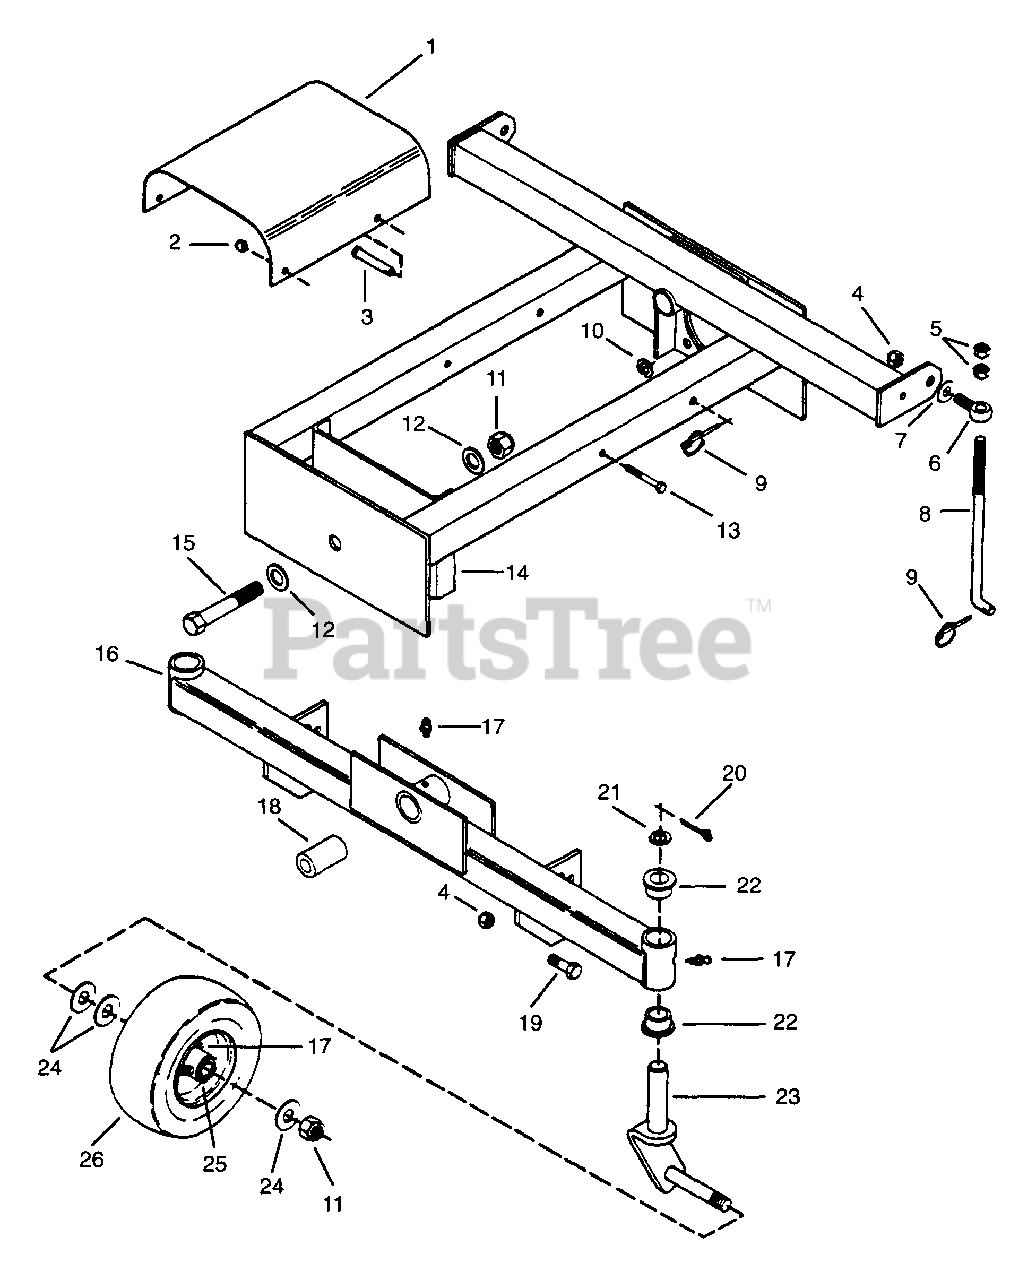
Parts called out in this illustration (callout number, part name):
1	Guard, PTO Shaft
2	Nut-Locking-Nylon .312-18 Grade 2
3	Pin-Clevis .38 x 2.62
4	Nut-Locking-Nylon .50-13 Grade 5
5	Nut-Jam .50-13 Grade 2
6	Bolt-Eye .56 x 2.12
7	Washer-Flat-Steel .500 x 1.250 x .083
8	Rod, Height Adjuster
9	Pin-Klik 1.000 x .188 x 1.25
10	Washer-Lock .50 Reg.
11	Nut-Locking-Nylon .75-10 Grade 2
12	Washer-Flat-Steel .700 x 1.470 x .134
13	Bolt-Hex .31-18 x 2.50 Grade 5
14	Weldment, Mower Frame
15	Bolt-Hex .75-10 x 4.50
16	Weldment, Axle
17	Fitting-Lube .25-28 x .256
18	Tube, Pivot
19	Bolt-Hex .50-13 x 1.375
20	Pin-Cotter .188 x 1.625
21	Washer-Hardened-Thrust 1.00 x 1.55 x .03
22	Bushing-Flange 1.020 x 1.385 x .75 x 1.75
23	Weldment, Caster Fork
24	Washer-Flat .812 x 1.469 x .134
25	Bearing, Gauge Wheel
26	Wheel 9 x 3.50
